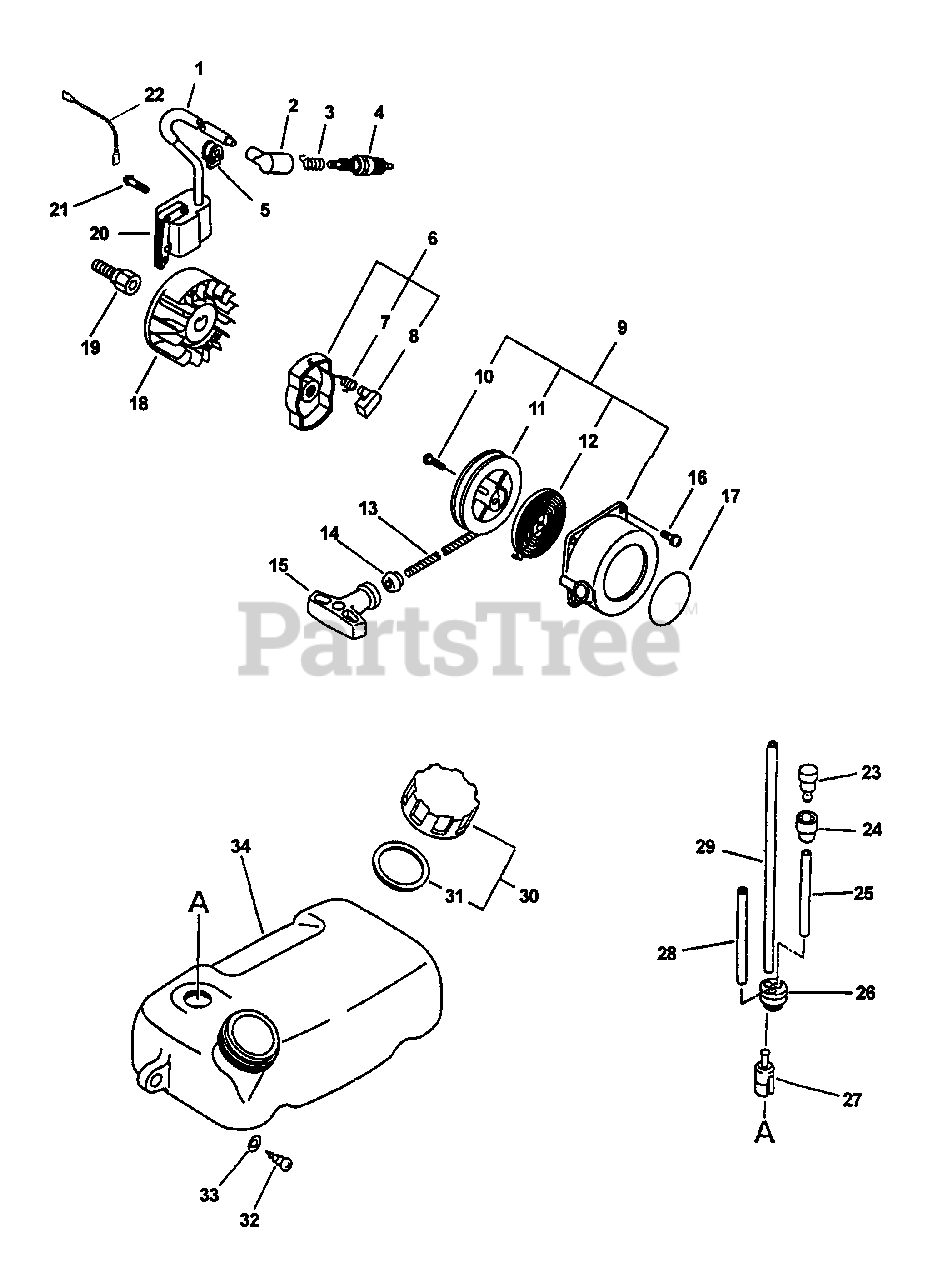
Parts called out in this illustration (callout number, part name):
2	CAP, SPARK PLUG
3	TERMINAL, SPARK PLUG
4	SPARK PLUG - BPM-7Y
6	PAWL ASSY, STARTER
7	SPRING, RETURN
8	PAWL, STARTER - BLACK
9	STARTER ASSY
10	SCREW
11	REEL, ROPE
12	SPRING, RECOIL
14	GUIDE, ROPE
15	GRIP, STARTER
16	BOLT 4×16
17	LABEL, ECHO
18	FLYWHEEL
19	HUB, FAN
20	COIL, IGNITION
21	SCREW 4×22
22	LEAD - GROUND
23	VENT ASSY
24	HOLDER, VENT
25	PIPE, FUEL 3×5×90 BLACK
26	GROMMET, FUEL
27	FILTER, FUEL
28	PIPE, FUEL RETURN 3×6×110
29	PIPE, FUEL 3×5×210 BLACK
30	CAP ASSY, FUEL
31	GASKET, FUEL CAP
32	SCREW, TAPPING 5×20
33	WASHER 5.5×12×0.8
34	TANK, FUEL
